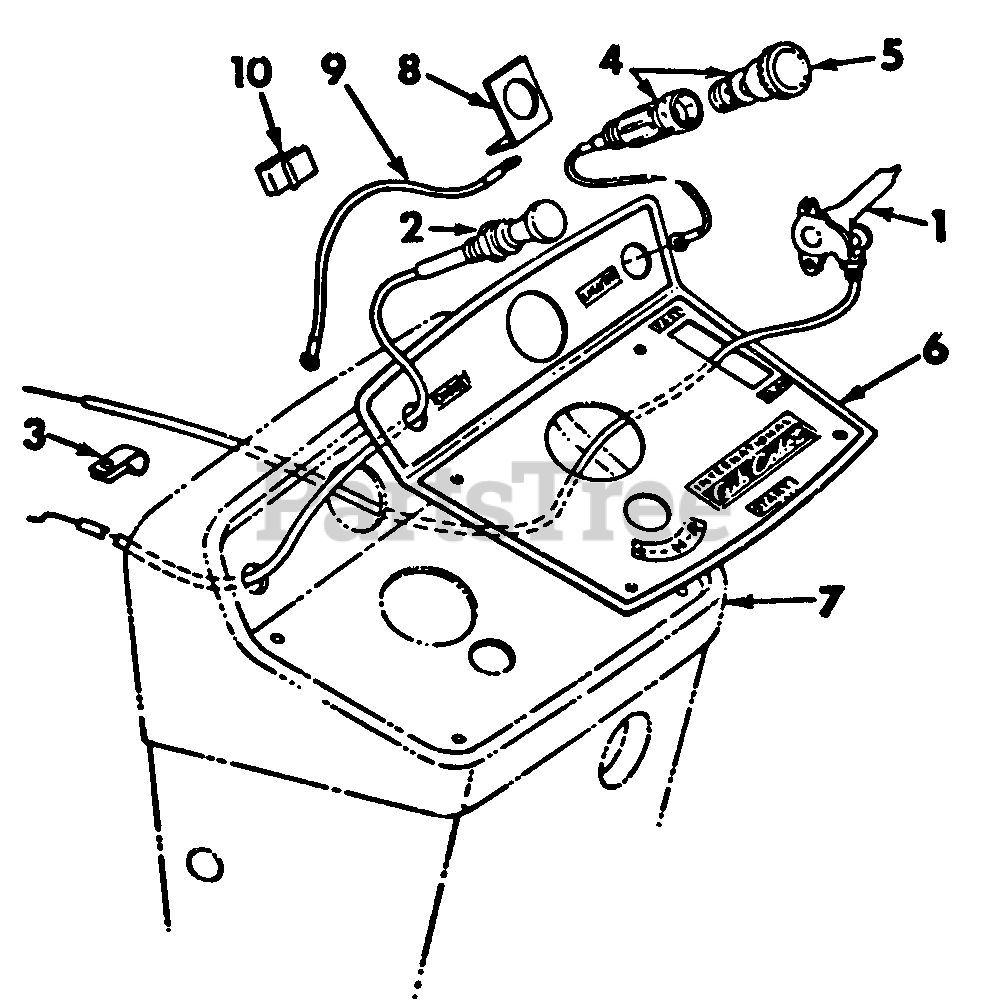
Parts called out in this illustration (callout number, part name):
1	Lever & Cable Assy, Throttle
2	Cable Assy, Choke
3	Clip, Throttle Cable Retainer
4	Cigarette Lighter Parts Accessory, 12 Volt
5	Unit, Pop-Out, Element
6	Product Graphic, Instrument Panel
7	Panel, Instrument
8	Bracket, Lighter Ground
9	Cable Assy, Ground
10	Clip, Cigarette Lighter Cable
